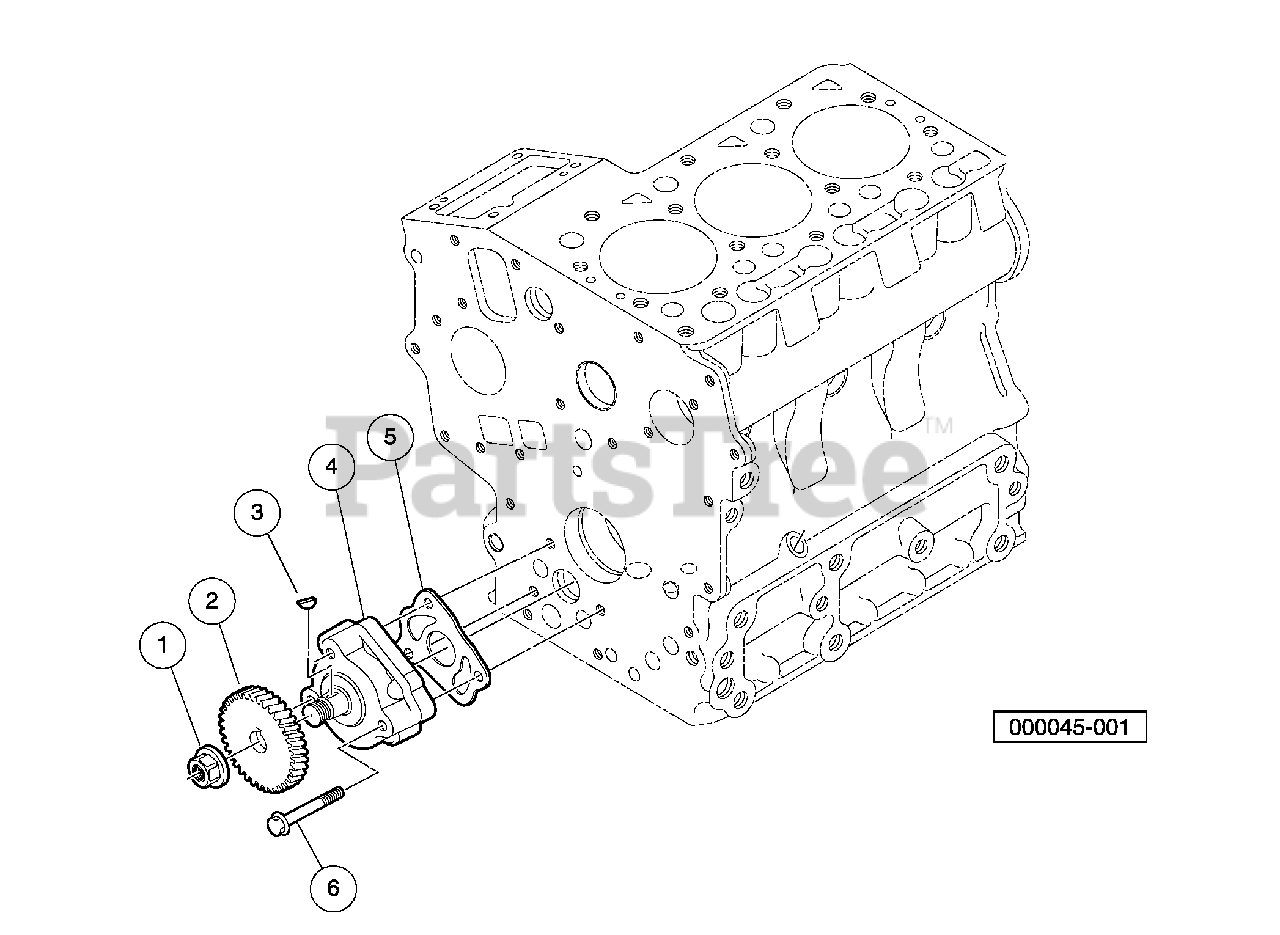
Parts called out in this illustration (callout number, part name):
1	Nut, Flange, D722 Oil Pump
2	Gear, Oil Pump Drive
3	Key, Feather, 8x4
4	Assy, Pump, Oil
5	Gasket, Oil Pump
6	Bolt, Oil Pump
